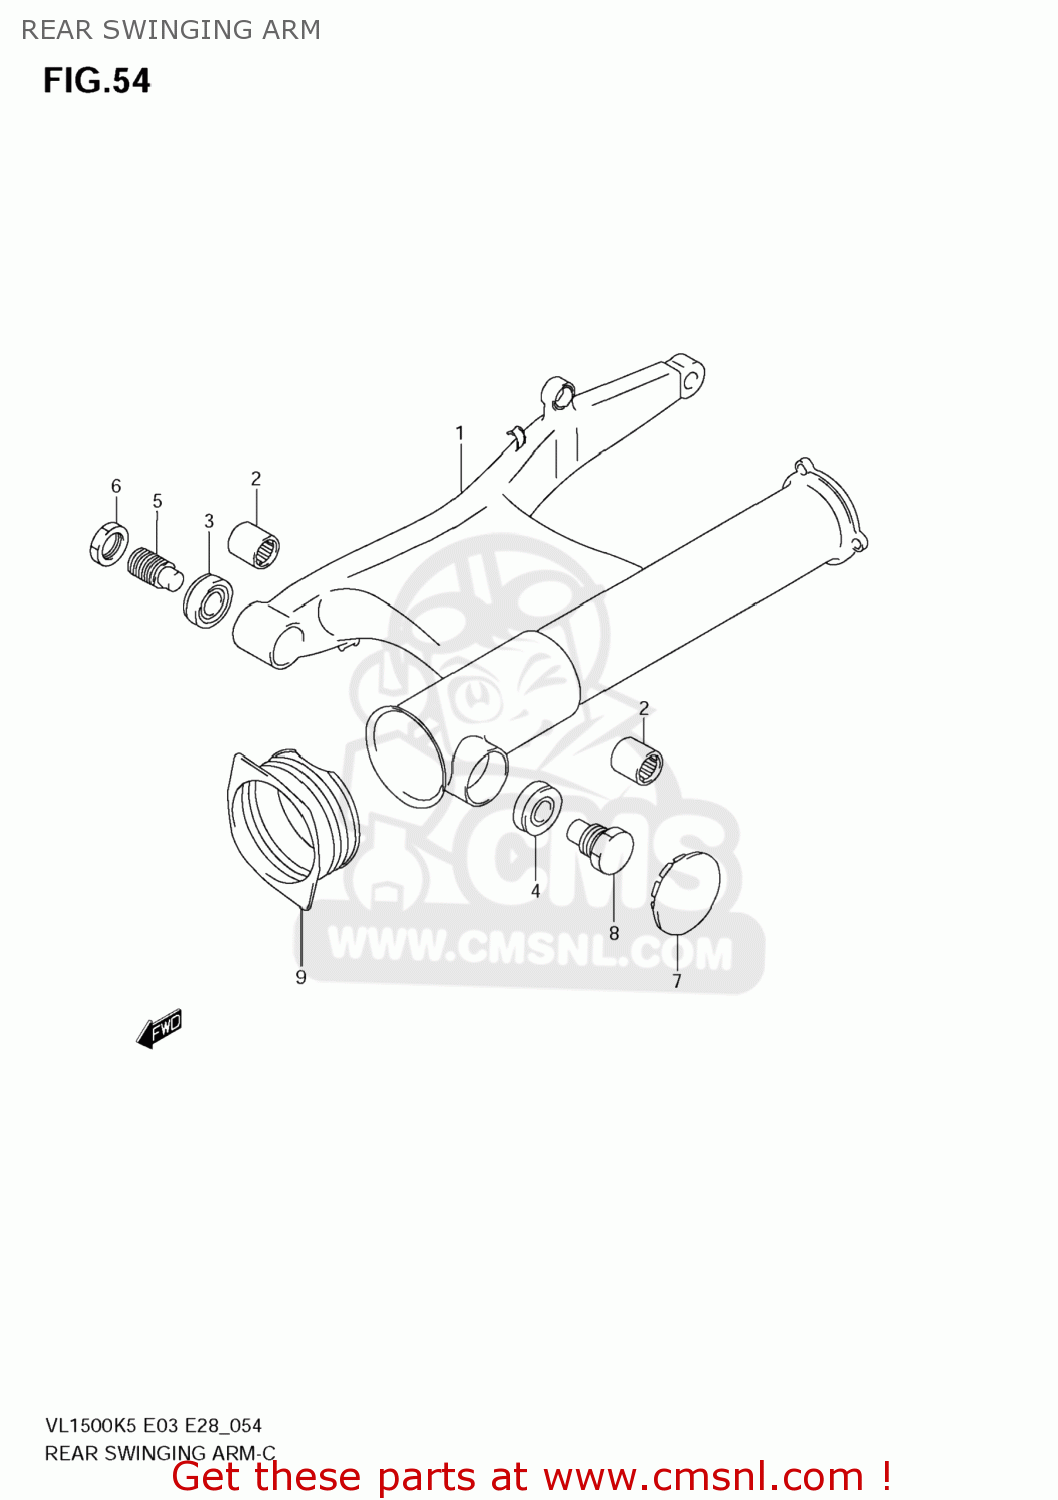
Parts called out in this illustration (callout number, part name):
1	SWINGINGARM SET,RR
2	BEARING(20X27X23.5)
3	BEARING(17X40X13.25)
4	BEARING(17X40X13.25)
5	BOLT,RR SWGARM PIVOT
6	NUT
7	CAP,RR SWINGING ARM PIVOT NUT
8	BOLT,SWINGINGARM PIVOT,L
9	BOOT,PROPELLER SHAFT
